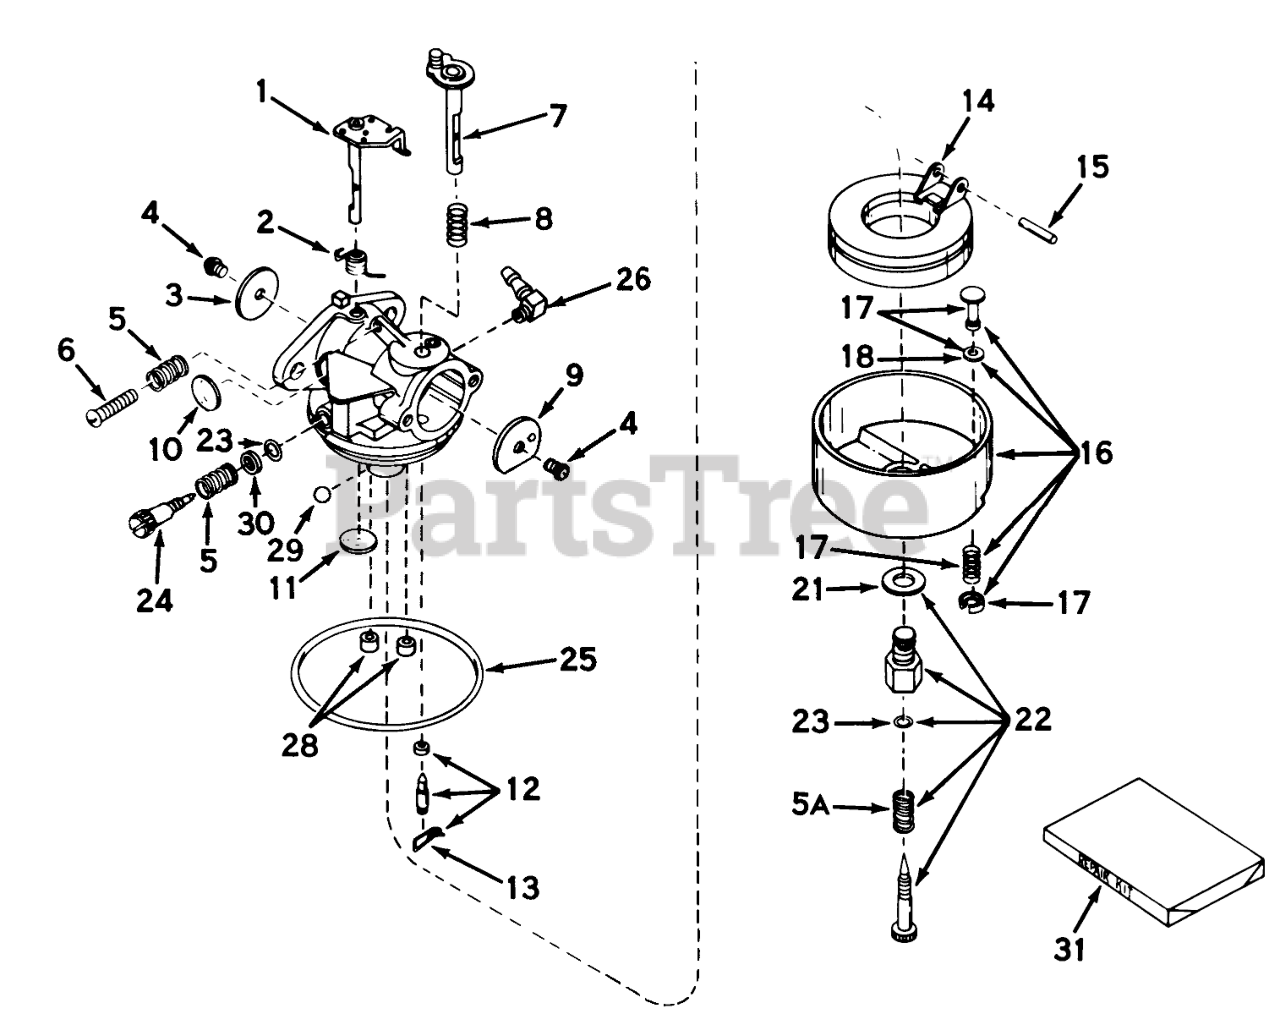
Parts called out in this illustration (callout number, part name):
1	Shaft & Lever Assy.
2	Spring, Throtte Return
3	Shutter-Throttle
4	Screw-Shutter
5	Spring-Tension
6	Screw-Throttle Crack Screw / Idle Speed
7	Shaft & Lever Assy., Choke
8	Spring, Choke return
9	Shutter-Choke
10	Plug-Welch, Idle Mixture Well
11	Plug-Welch, Atmospheric Vent
12	Inlet Needle, Seat & Clip Assy.(Incl. No. 13)
13	Clip-Spring
14	Float,Carburetor
15	Shaft-Float
16	Bowl & Drain Assy., Float (Incl. Nos. 17 & 18)
17	Plunger Assy., Drain (Incl. No. 18)
18	Gasket-Plunger, Drain
21	Washer-Bowl Nut
22	Adjustment Screw Assy., Main (Incl. Nos. 5A, 21 & 23)
23	"O"Ring
24	Screw, Idle Adj.
25	O Ring-Bowl, Float
26	Fitting Fuel Inlet
28	Plug, Cup
29	BalI, Steel
31	Kit-Repair
